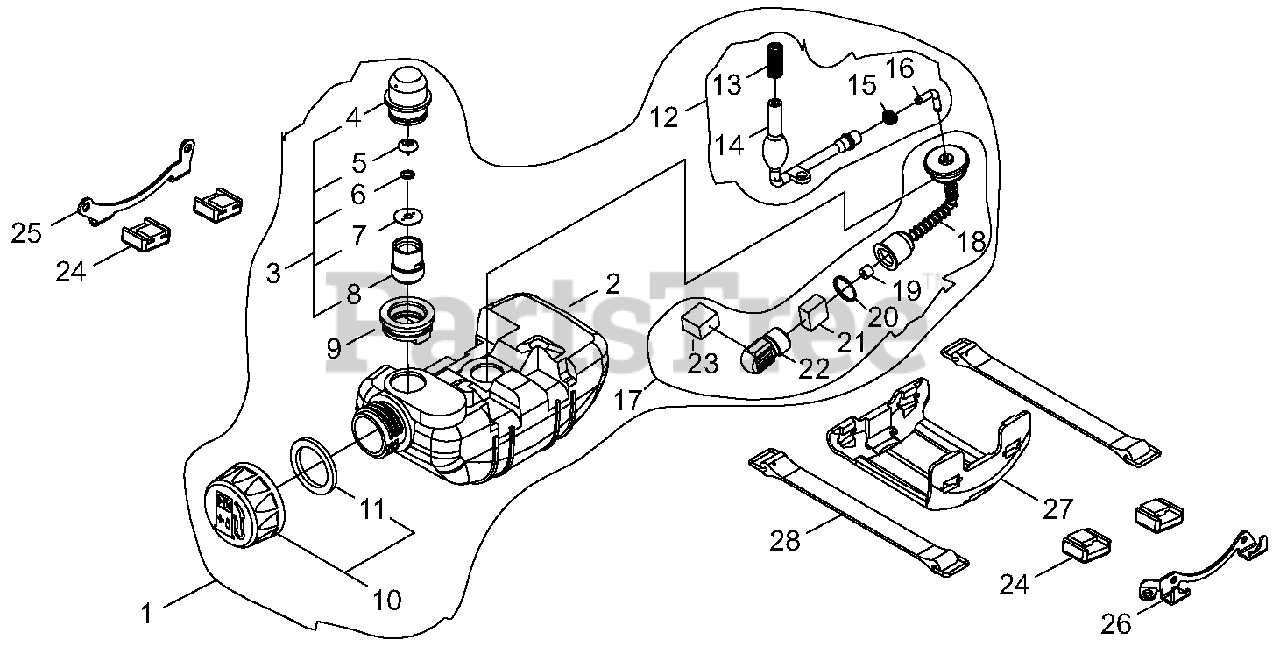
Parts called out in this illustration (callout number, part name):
1	FUEL TANK ASSY
2	TANK, FUEL
3	VENT ASSY
4	CAP, BREATHER
5	VENT, FUEL TANK
6	WASHER
7	RETAINER
8	HOLDER, VENT
9	GROMMET
10	CAP ASSY
11	GASKET, CAP
12	FUEL PIPE ASSY
13	CLAMP
14	PIPE - FUEL
15	CLIP - 7.8
16	CONNECTOR, PIPE
17	FUEL FILTER ASSY
18	PIPE - FUEL
19	VALVE, CHECK
20	CLIP
21	FILTER, FUEL - B
22	WEIGHT, FUEL FILTER
23	FILTER, FUEL - A
24	CUSHION
25	BRACKET - INNER
26	BRACKET - OUTER
27	GUARD, FUEL TANK
28	STRAP, FUEL TANK
